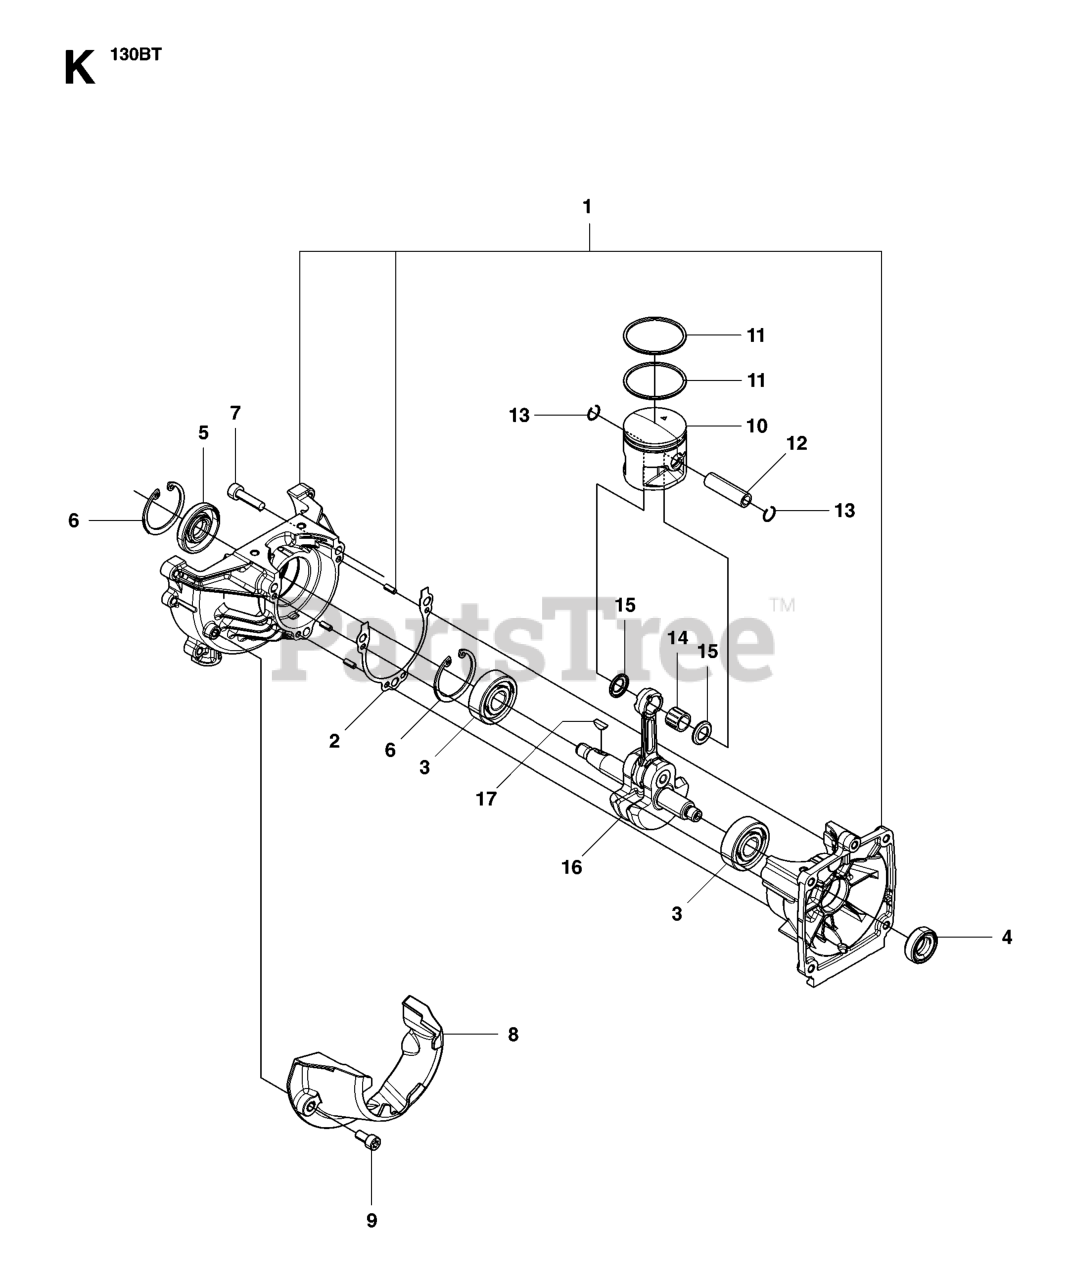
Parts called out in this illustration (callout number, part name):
1	CRANKCASE-C
2	GASKET CASE
5	SEAL
7	BOLT
8	COVER, CASE
9	BOLT 08
10	PISTON
16	CRANKSHAFT C
17	KEY
